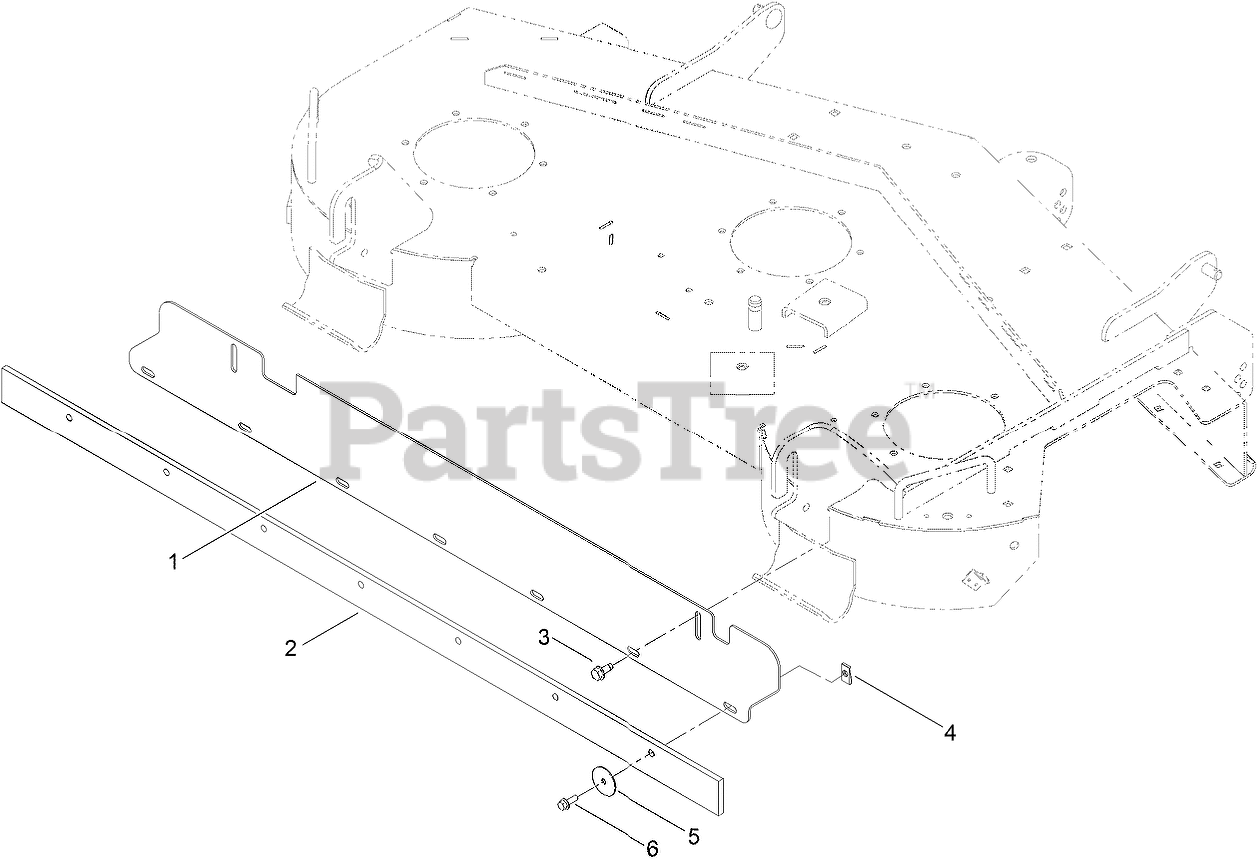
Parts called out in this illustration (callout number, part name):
1	BRACKET-STRIPING
3	SCREW-HWHTF
4	NUT-SPEED
5	WASHER-FENDER
6	SCREW-HHF
